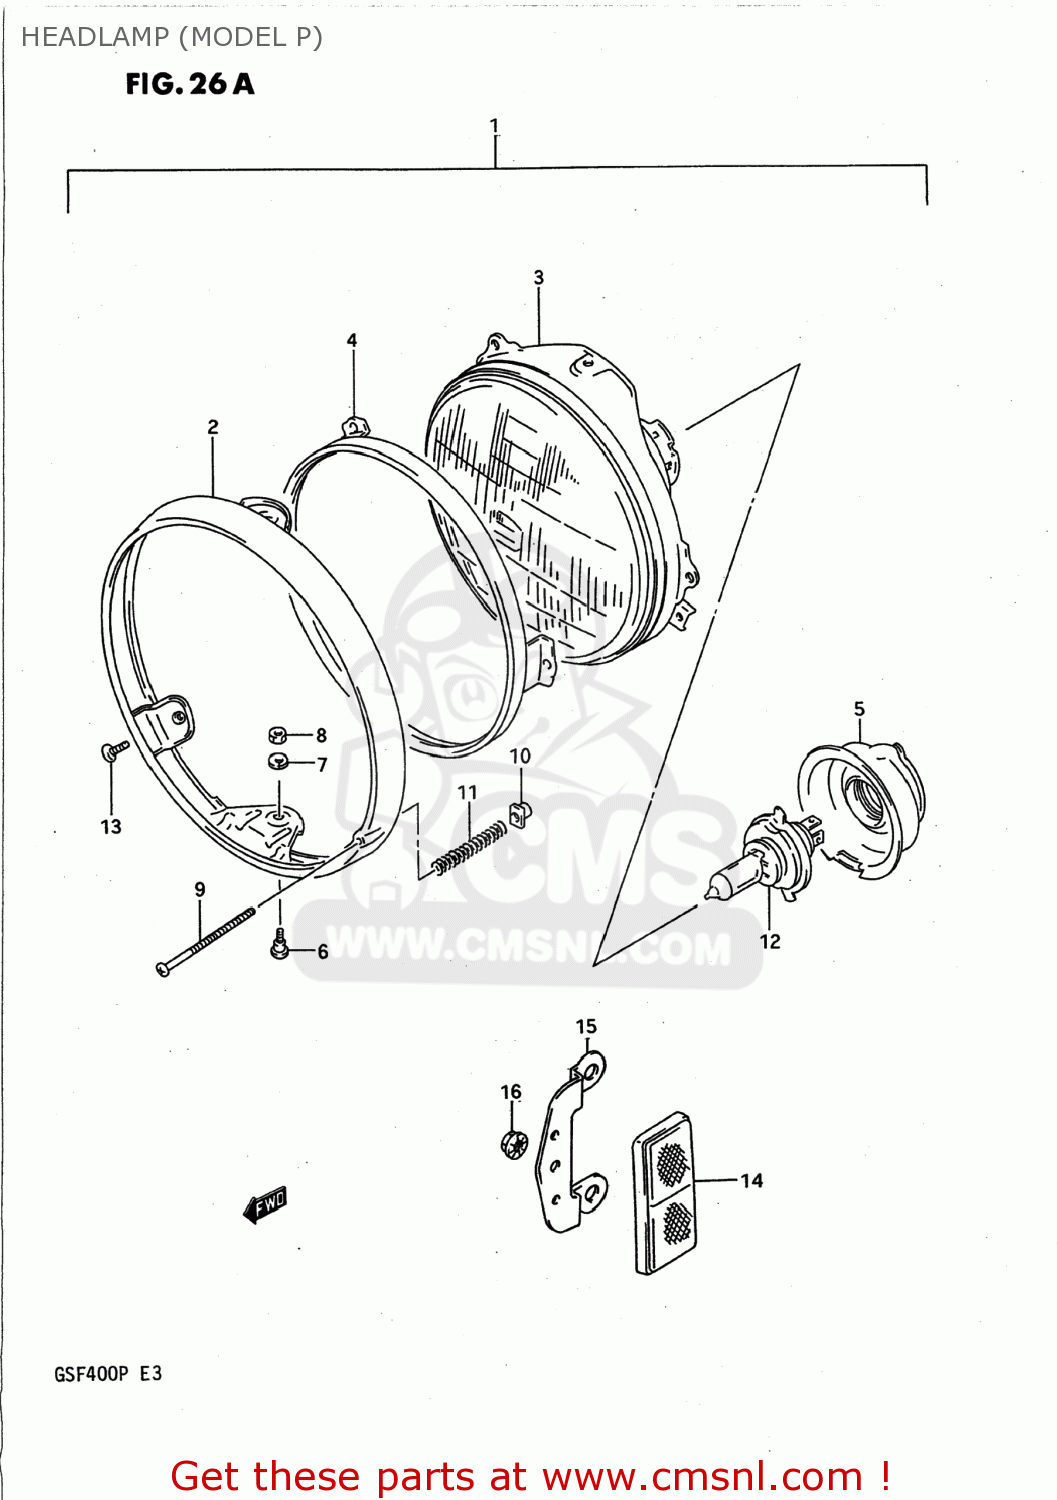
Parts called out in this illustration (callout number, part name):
1	HEADLAMP ASSEMBLY
2	RIM,HEADLAMP
3	LAMP UNIT
4	RETAINING RING
5	COVER,SOCKET
6	H/LAMP LENS UNIT FITING SCRE
7	LOCK WASHER
8	NUT
9	SCREW,HEADLAMP ADJUST
10	NUT
11	SPRING,ADJUSTING
12	BULB(12V60/55W,H4)
13	SCREW 5X12
14	REFLEX REFLECTOR,FR SIDE
15	BRACKET,FRONT SIDE REFLECTOR
16	NUT
